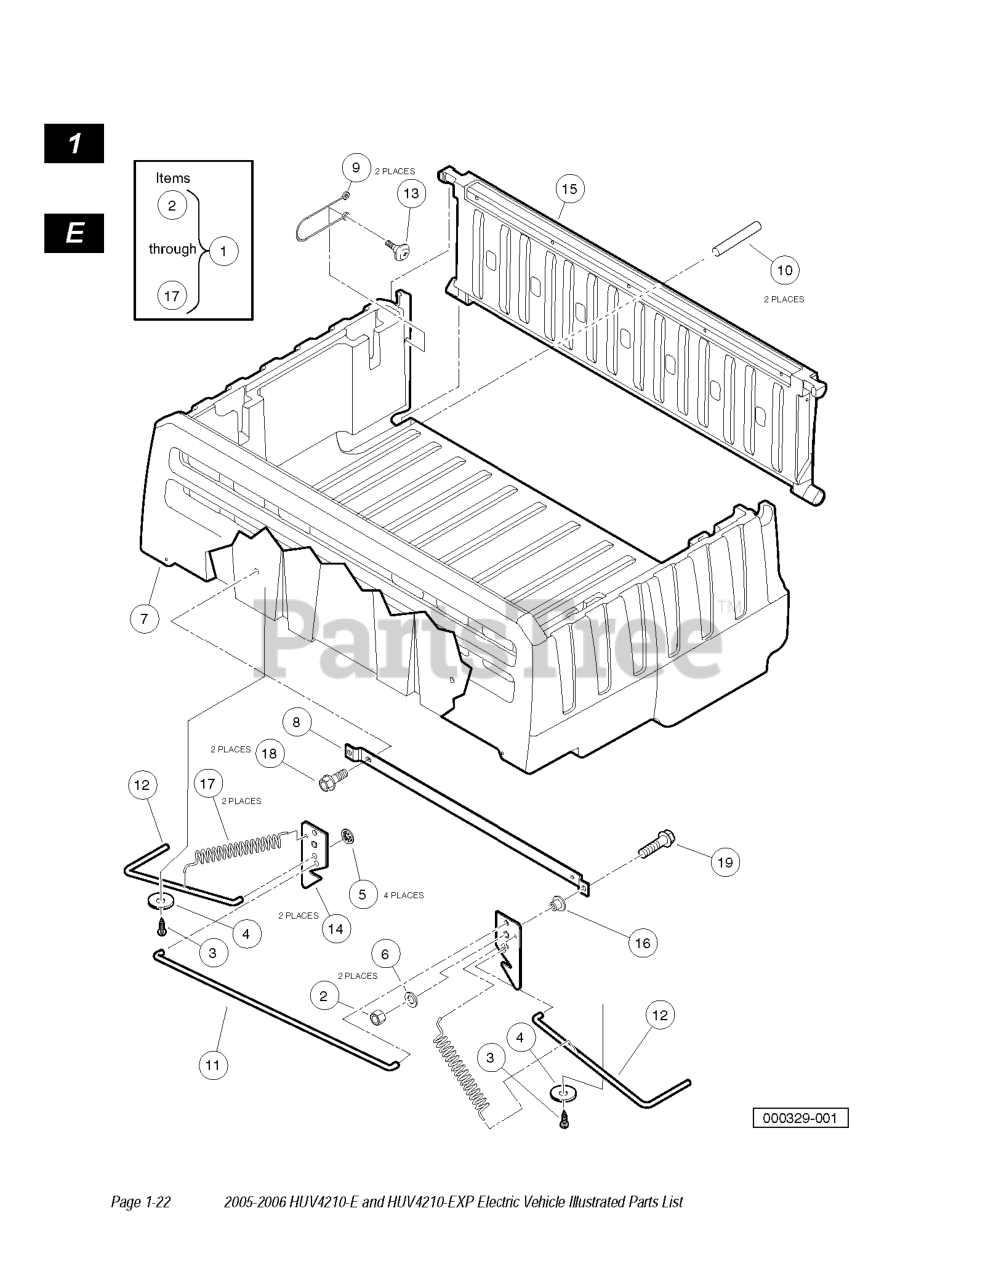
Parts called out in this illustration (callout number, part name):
1	BED ASM - 4200 SERIES
2	LOCKNUT, DIMPLED
3	SCREW, HEX WASH
4	WASHER, 5/16 TYPE B FLAT
5	PUSHNUT, 3/8
6	Washer, 3/8 Flat Type A
7	Bed, Cargo
8	Support, Latch Link
9	LANYARD, TAILGATE
10	Pin, Support
11	Rod, Long Link
12	Rod, Bed Lift, Short Bent
13	BOLT LANYARD
14	Catch, Tilt Bed
15	TAILGATE, HUSQVARNA
16	Bearing, Bronze, 1/2 x 9/32
19	SCREW, CAP, HEX HD 3/8-16X1.00
